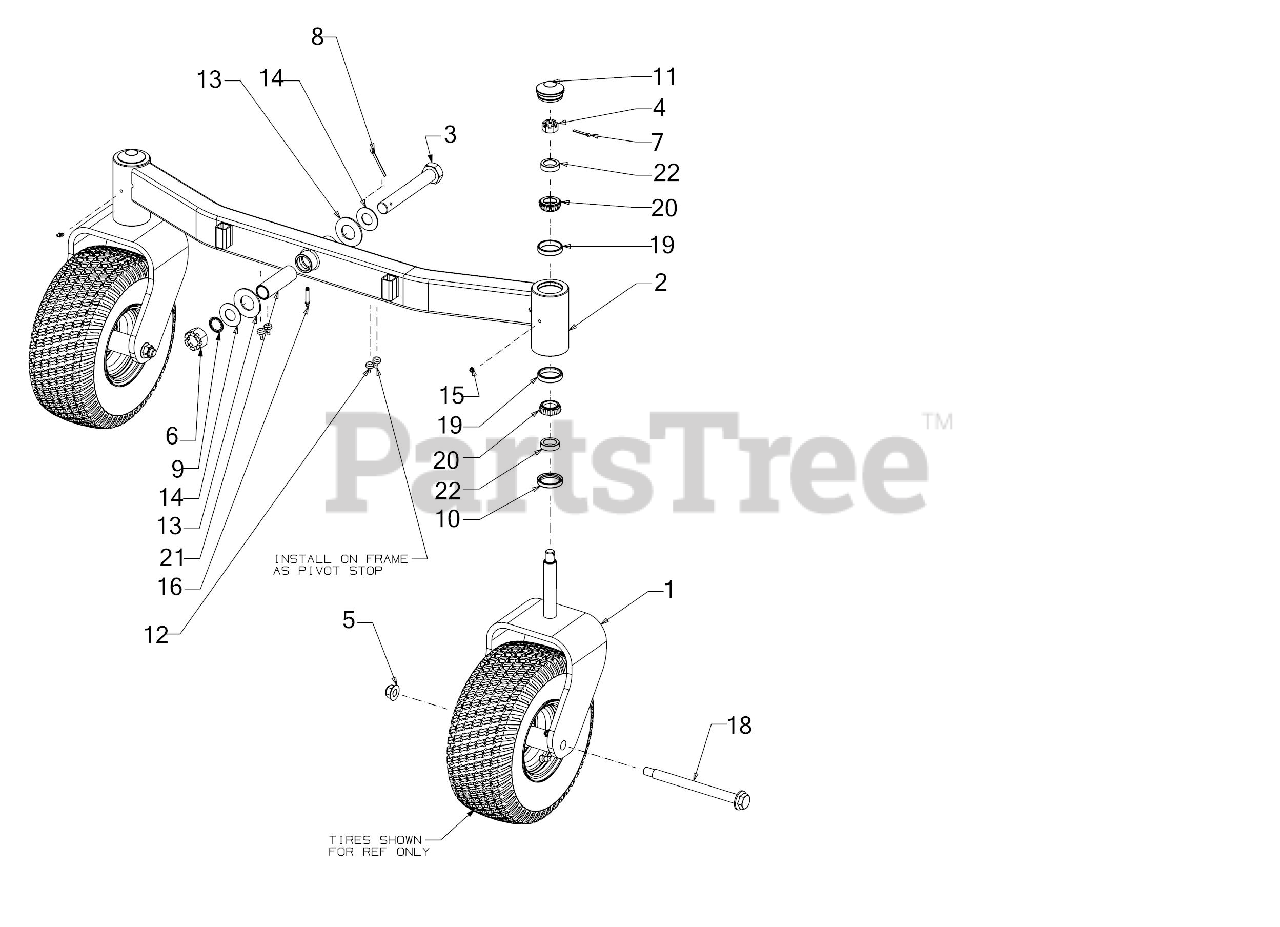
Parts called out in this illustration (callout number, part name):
1	FRONT CASTER ASSEMBLY (LAPBAR)
2	FRONT AXLE ASSEMBLY
3	HEX HEAD SCREW 1-14 X 7 GR5
4	HEX NUT CASTLE 3/4-16
5	FLANGE LOCK NUT
6	CASTLE NUT 1.0-14 GR5
7	COTTER PIN-5/32 DIA
8	COTTER PIN
9	RETAINING RING
11	AXLE GREASE CAP
12	BUMPER, .62 DIA x .3
13	BELL WASHER 1.25ID x 2.5 x .180
14	FLAT WASHER 1.0 x 2.0 x .075
15	GREASE ZERT 1/4-28
16	GREASE FITTING
18	SHOULDER BOLT .750 X 8.175:5/8-11
19	BEARING CUP
20	BEARING CONE
